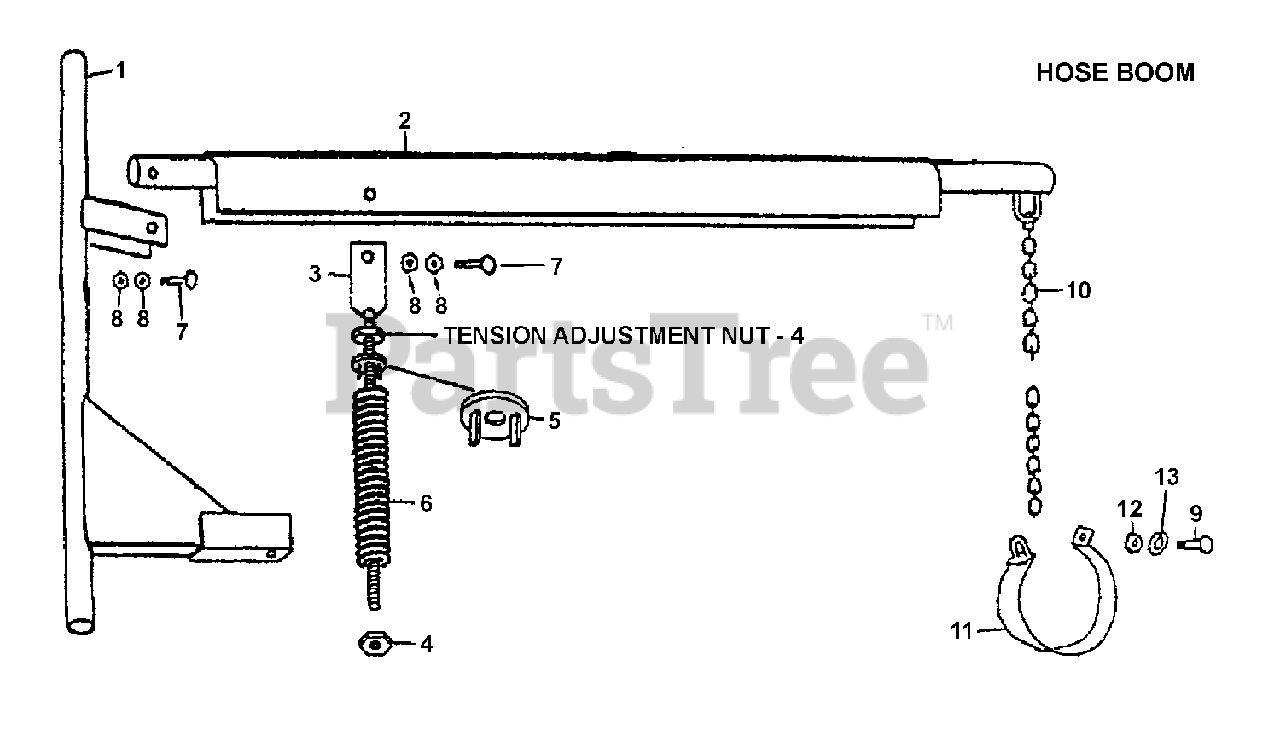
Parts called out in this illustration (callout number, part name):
1	Boom Vertical Member
2	Boom Horizontal Member
3	Threaded Spring Guide
4	3/4 Nut
5	3/4 Flat Washer
6	Boom Coil Spring
7	1/2 x 3 Hex Bolt
8	1/2 Lock Nut
9	5/16 x 3-1/2 Hex Bolt
10	Boom Chain
11	Hose Support Band 12in
11	Hose Support Band 16in
12	5/16 Hex Nut
13	5/16 Washer
